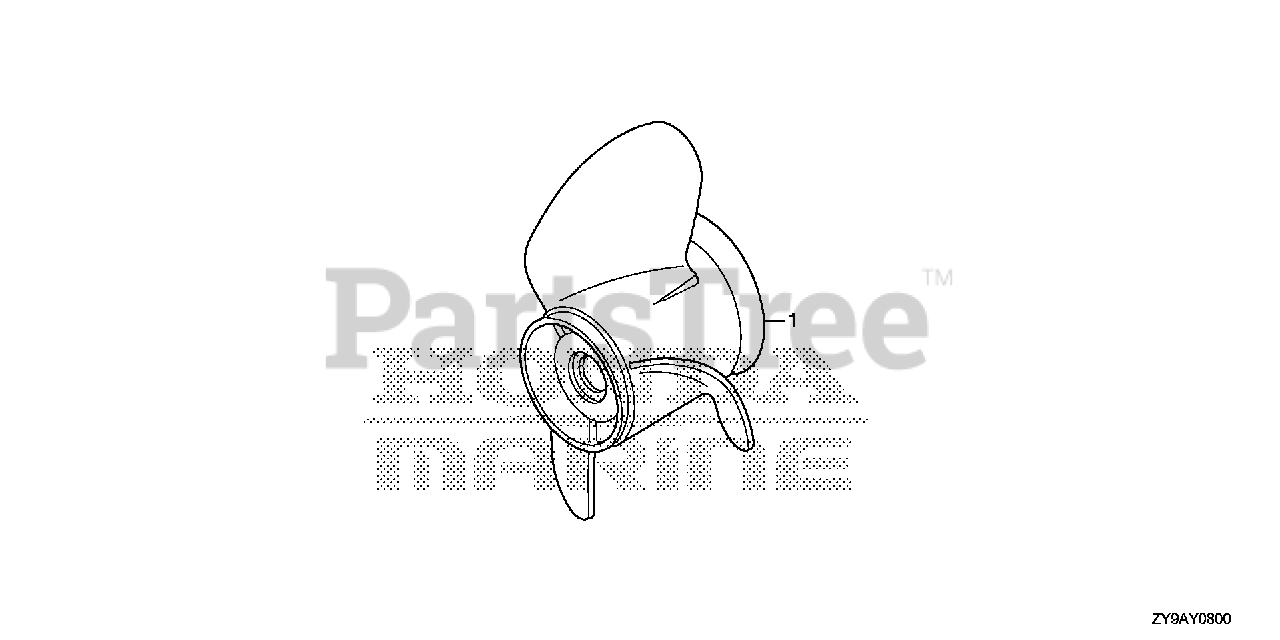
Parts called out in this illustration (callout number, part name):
1	PROPELLER, THREE-BLADE (13X19) (SUS)
1	PROPELLER, THREE-BLADE (13X21) (SUS)
1	PROPELLER, THREE-BLADE (14X11) *NH283* (AL) (STIN GRAY)
1	PROPELLER, THREE-BLADE (13-3/4X13) *NH283* (AL) (STIN GRAY)
1	PROPELLER, THREE-BLADE (13-1/2X15) *NH283* (AL) (STIN GRAY)
1	PROPELLER, THREE-BLADE (13-1/4X17) *NH283* (AL) (STIN GRAY)
1	PROPELLER, THREE-BLADE (13X21) *NH283* (AL) (STIN GRAY)
1	PROPELLER, THREE-BLADE (13X19) *NH283* (AL) (STIN GRAY)
1	PROPELLER, THREE-BLADE (13-1/4X17) (SUS)
1	PROPELLER, THREE-BLADE (13-1/4X15) (SUS/HAC)
1	PROPELLER, THREE-BLADE (13-1/4X17) (SUS/HAC)
1	PROPELLER, THREE-BLADE (13-1/4X19) (SUS/HAC)
1	PROPELLER, THREE-BLADE (13-1/4X21) (SUS/HAC)
1	PROPELLER, THREE-BLADE (13-1/5X19) *NH283* (STIN GRAY)
1	PROPELLER, THREE-BLADE (13-1/5X21) *NH283* (STIN GRAY)
1	PROPELLER, THREE-BLADE (13-1/2X14) *NH283* (STIN GRAY)
